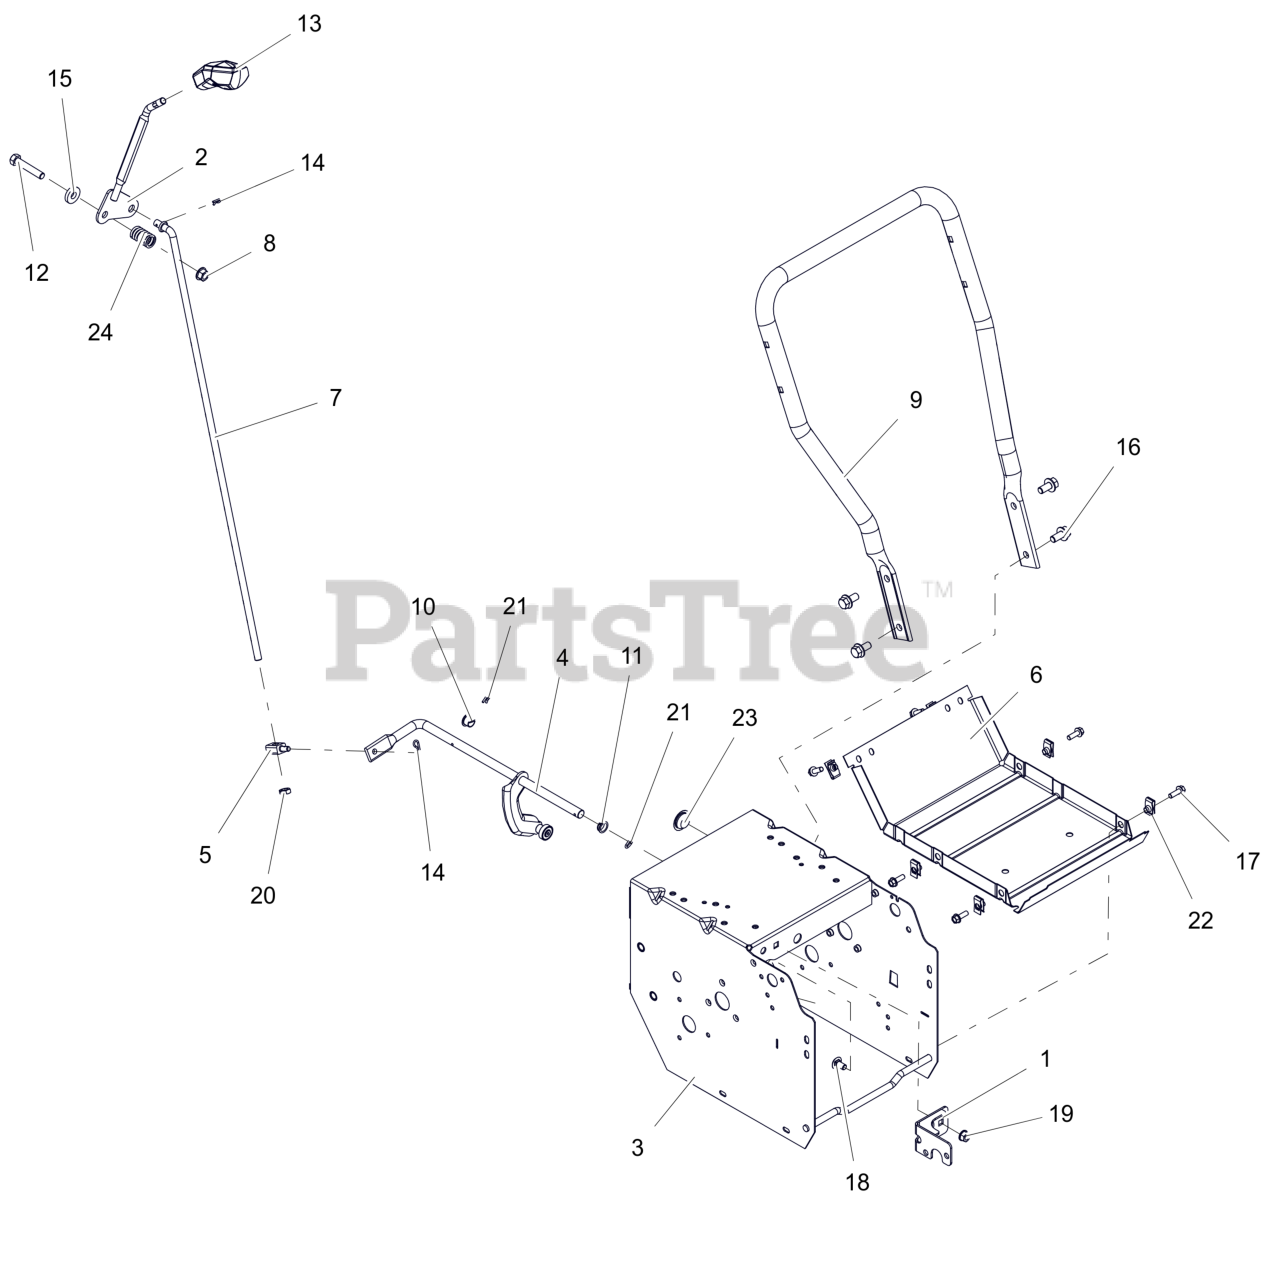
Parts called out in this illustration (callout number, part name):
1	WELDMENT, FRAME BRACKET
2	LEVER, CONTROL-SHIFT(WELDMENT)
3	WELDMENT, FRAME - DELUXE 16"
4	ARM, SHIFT-SMALL DASH (ASSY)
5	PIVOT,SHIFT ROD .375-16(TRUNN)
6	COVER, BOTTOM
7	ROD, SHIFT - COMPACT
8	NUT-LK-TOP-FLG .38-16 ZC120
9	HANDLEBAR, LOWER - SM DELUXE
10	BUSHING, POLYLINER-.50 SPLIT
11	BUSHING, POLYLINER-.50 SNAPIN
12	BLT,HEX .38-16X2.00 G5 ZCC
13	KNOB, CONTROL
14	PIN, HAIR #213 .08X1.19 ZCC
15	WSHR, FLT .406X1.00X.188 ZCC
17	BLT, HWH .25-20X.75 G5 ZCC
18	BLT, RHSSN .31-18X.625 G5 ZCC
19	NUT-LK-TOP-FLG .312-18 GF ZCC
20	NUT-JAM .375-16 G2 ZCC
21	CLIP, SPRING
22	NUT-RTNR .25-20X.56
23	PLUG, HOLE - .875" NYLON
24	SG-COMP .125X.781X1.250
